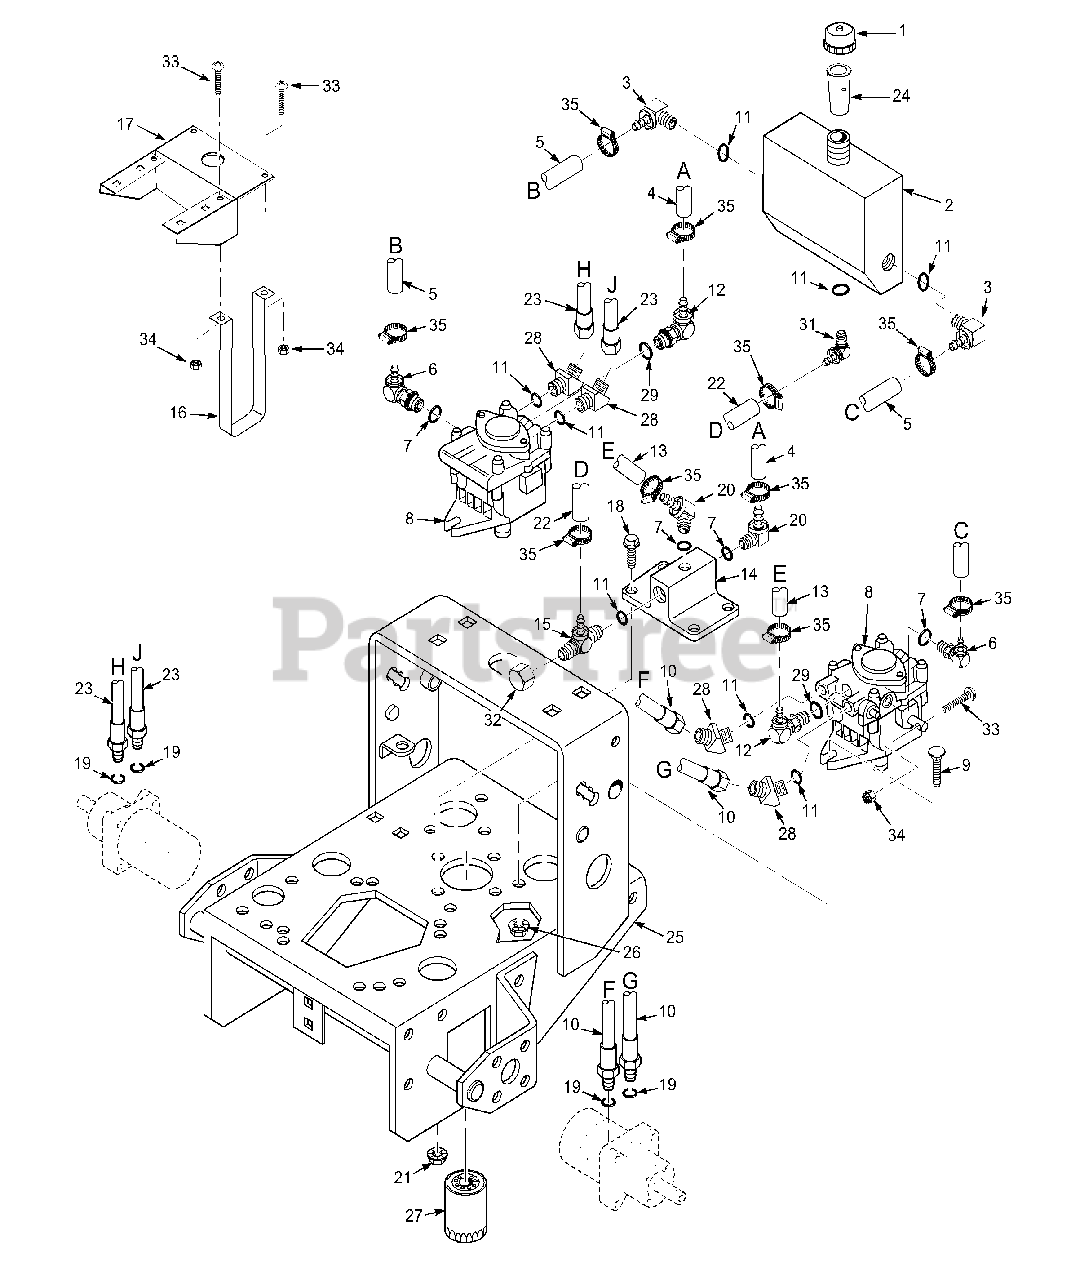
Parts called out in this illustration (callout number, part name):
1	Cap, Oil Reservoir
2	Oil Reservoir (With Fittings)
3	Elbow, 9/16 O-Ring x 3/8 Hose
4	Hose, 3/8" ID - 16" Long (Order By The Inch)
5	Hose, 3/8" ID - 7" Long (Order By The Inch)
6	Elbow, 90 deg. 7/16-20 JIC to 9/16-18 "O" Ring
7	O-Ring
8	Pump, Hydro-Gear BDP-10L117
9	Bolt, Carriage, 3/8-16 x 1.25"
10	Hose, Pump to Wheel Motor
11	O-Ring
12	Elbow, 7/16 O-Ring x 3/8 Hose
13	Hose, 3/8" ID - 10-1/4" Long (Order By The Inch)
14	Oil Filter Base
15	Tee, 3/8 O-Ring x JIC x 1/2 Hose
16	Strap, Hydraulic Tank
17	Bracket, Hydraulic Tank
18	Capscrew, 5/16-18 x .75" Serr. Flange
19	O-Ring
20	Elbow, 9/16 O-Ring x 3/8 Hose
21	Nut, 5/16-18 Serr. Flange
22	Hose, Formed 1/2" ID
23	Hose, Pump to Wheel Motor
24	Tube, Filler Neck
25	Engine Deck (16" Wide) W/Decals - Small Frame
26	Nut, 3/8-16 Serr. Flange
27	Oil Filter
28	Elbow, 45 Deg.-3/4-16 JIC Male x Male 3/4-16 O-Ring
29	O-Ring
31	Elbow, 3/4-16 O-Ring x 1/2 Hose
32	Cap, 3/4-16
33	Screw, 1/4-20 x 2.0" Round Head Phillips
34	Nut, 1/4-20
35	Clamp, .87 max dia.
